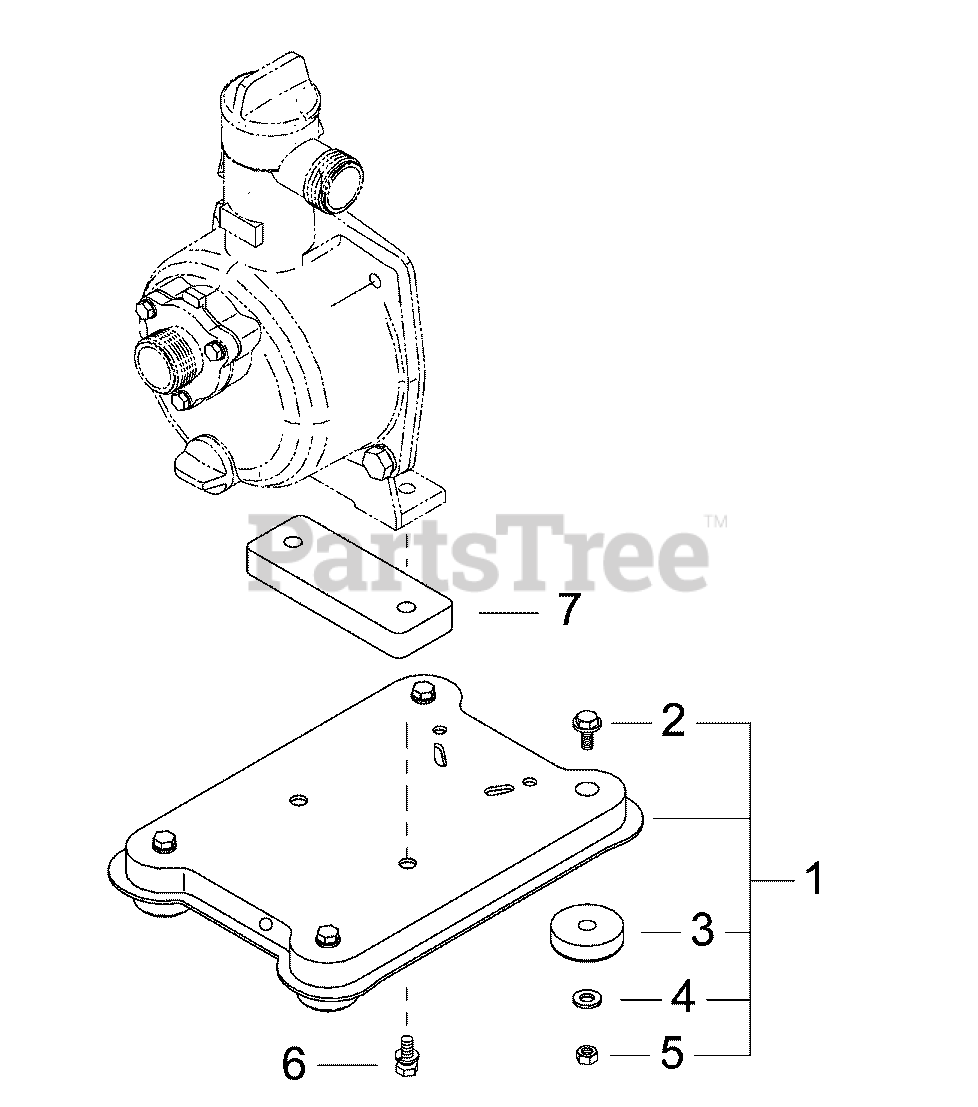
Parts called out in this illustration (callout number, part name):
1	BASE, PURGE
2	BOLT - 6X16
3	CUSHION
6	BOLT - 8X25
7	SPACER - 9
